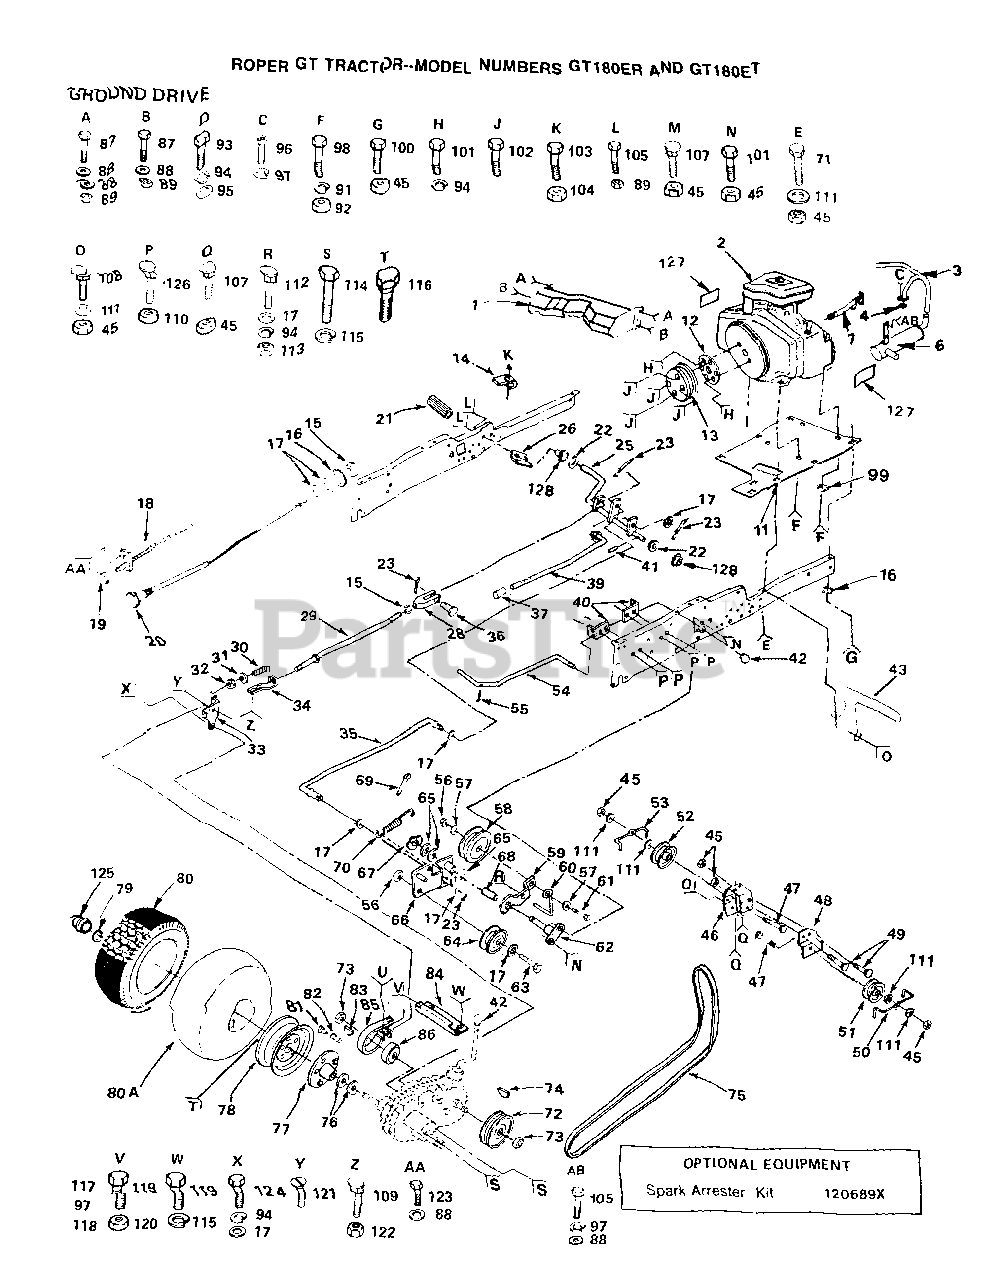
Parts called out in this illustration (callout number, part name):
1	BAFFLE ASSY - ENGINE
11	"ENG. T, BASE"
12	ADAPTER T
14	ACT-SWITCH T
16	LOCKWASHER
17	WASHER
21	PEDAL COVER T
25	SHAFT ASSY GT
26	BRKT SWITCH GT
28	YOKE GTV
29	BRAKE ROD T
30	SPRING T
31	WASHER
33	BRAKE BRKT ASSY T
34	GUIDE ROD T
35	ROD CLUTCH GTV
36	CLEVIS PIN T
37	PLUNGER CAP T
40	ROD BRACKET GT
41	ROLL PIN STD
43	GUARD MUFFLER HYT
47	BOLT
49	BOLT
50	BELT GUARD T
51	IDLER-FLAT T
52	PULLEY V IDLR GTV
54	ROD SHIFT GTV
56	LOCKNUT
57	WASHER
60	BELT RETAINER GT
62	BRACKET ASSY GTV
65	WASHER T
66	CLUTCH BRACKET GT
67	KLIP RING
68	"GTV, BEARING"
69	COTTER PIN
70	SPRING GTV
71	BOLT
72	PULLEY GT
73	NUT STD
75	BELT-V.98.5.GD.DV
76	WASHER T
79	KLIP RING
80A	TUBE.23X8/10-12
81	VALVE CAP
82	VALVE STEM LT
86	BRAKE DRUM T
88	WASHER
91	LOCKWASHER
92	NUT.HEX.5/16-18
94	LOCKWASHER
95	WASHER
97	LOCKWASHER
98	BOLT
99	LOCKWASHER.5/16.E
101	BOLT
103	SCREW
105	BOLT LT
107	BOLT
108	BOLT.3/8-14X1.25
111	WASHER GT
113	NUT.HEX.3/8-16UNC
114	BOLT
115	LOCKWASHER
116	BOLT
117	BOLT T
119	BOLT
120	NUT GTV
121	SCREW
122	No Desciption for Part
123	SCREW
125	CAP-HUB GT
126	BOLT
128	NYLINER T
120689X	SPARK ARRESTER KIT
